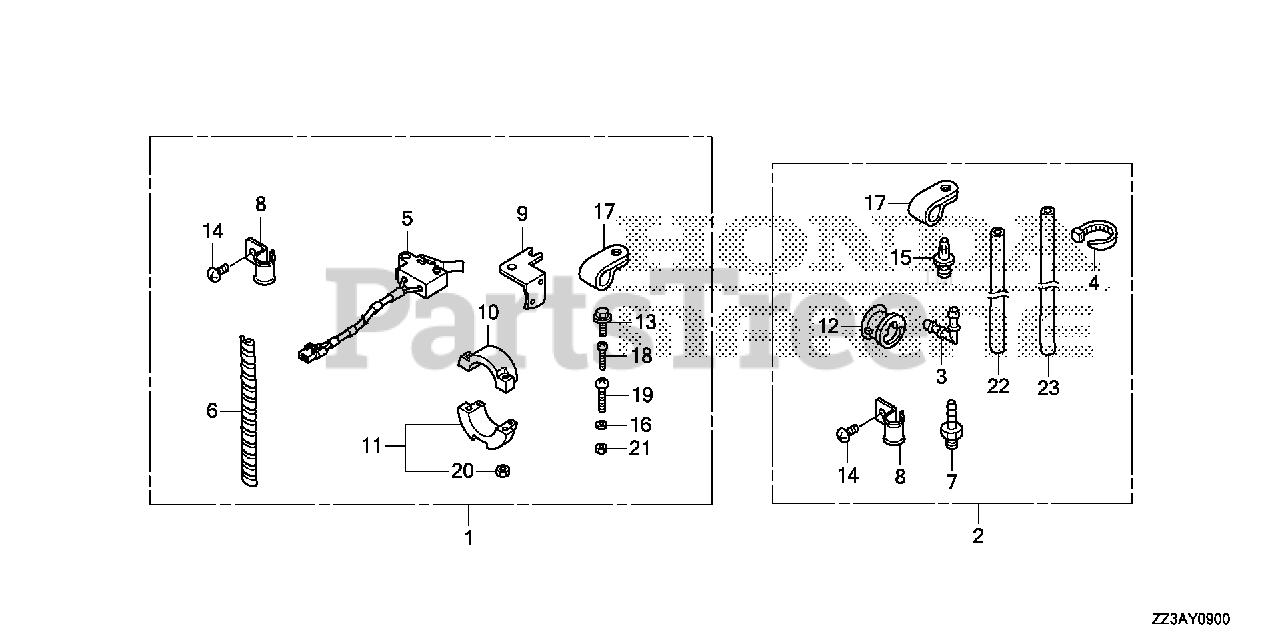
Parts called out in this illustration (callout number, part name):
1	LIMIT KIT, TILT
2	TUBE KIT, SPEED SENSOR
3	JOINT A, BREATHER
4	BAND, WIRE
5	SWITCH ASSY., TILT LIMIT
6	TUBE, SPIRAL
7	NIPPLE, SENSOR
8	CLAMP, TUBE
9	BRACKET, TILT LIMIT SENSOR
10	CAM A, TILT LIMIT ANGLE
11	CAM B, TILT LIMIT ANGLE
12	BUSH, MOTOR CODE
13	BOLT, FLANGE (6X12)
14	SCREW, PAN (6X8)
15	SCREW, RIVET (5X10)
16	WASHER, PLAIN (4MM)
17	CLIP (14MM)
18	SCREW, PAN (4X14)
19	SCREW, PAN (5X20)
20	NUT, HEX. (5MM)
21	NUT, HEX. (4MM)
22	BULK HOSE, VACUUM (5X3000) (5X530)
23	BULK HOSE, VACUUM (5X3000) (5X950)
